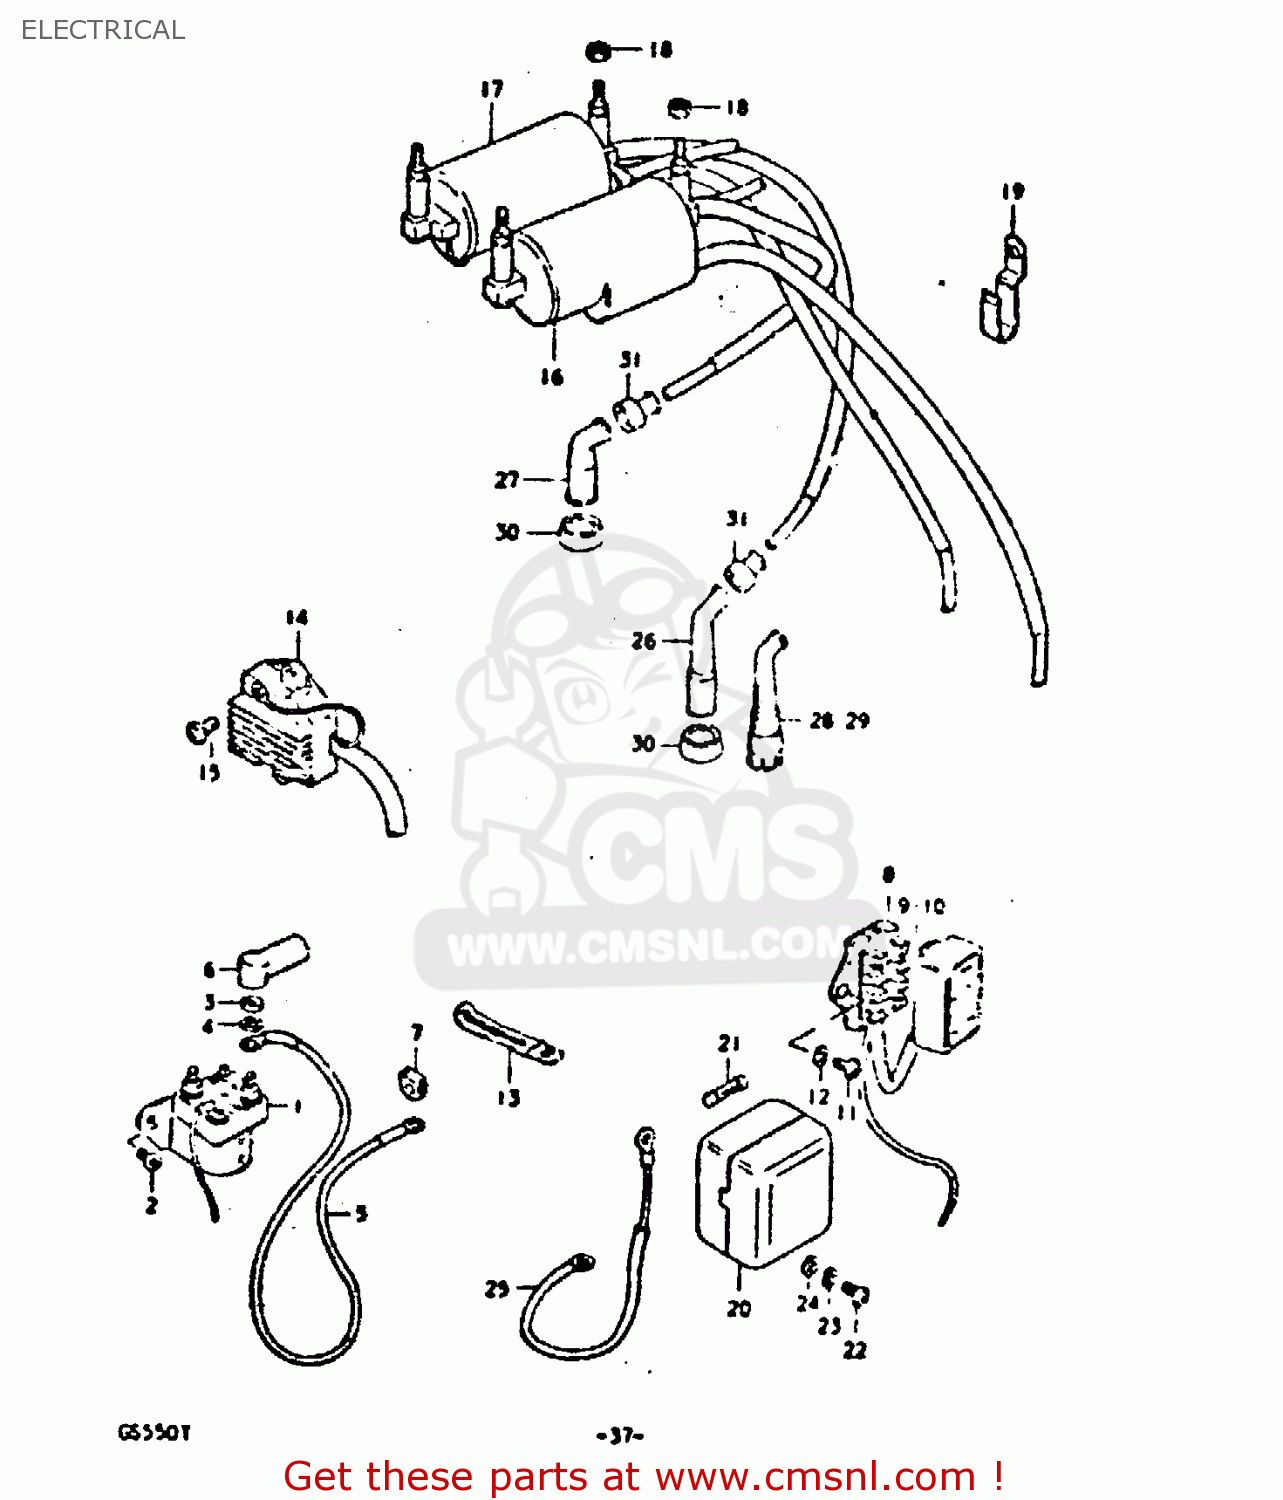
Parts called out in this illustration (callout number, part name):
1	RELAY ASSY,STARTING MOTOR
2	SCREW
3	NUT 6MM
4	LOCK WASHER
5	WIRE,STARTER MOTOR LEAD
6	CAP,STARTER RELAY
7	GROMMET,STARTER CABLE
8	BOX ASSEMBLY,FUSE
9	FUSE(15A)
10	FUSE(10A)
11	SCREW 6X12
12	WASHER
13	CLAMP
14	RECTIFIER ASSEMBLY
15	SCREW
16	COIL ASSEMBLY,IGNITION
17	COIL ASSEMBLY,IGNITION
18	NUT
19	CLAMP
20	TERMINAL ASSEMBLY,POWER SO
21	FUSE(10A)
22	SCREW
23	LOCK WASHER
24	WASHER
25	WIRE,POWER SOURCE LEAD
28	CAP,SPARK PLUG
29	CAP, SPARK PLUG (S)
30	SEAL,SPARK PLUG
31	SEAL,SPARK PLU
